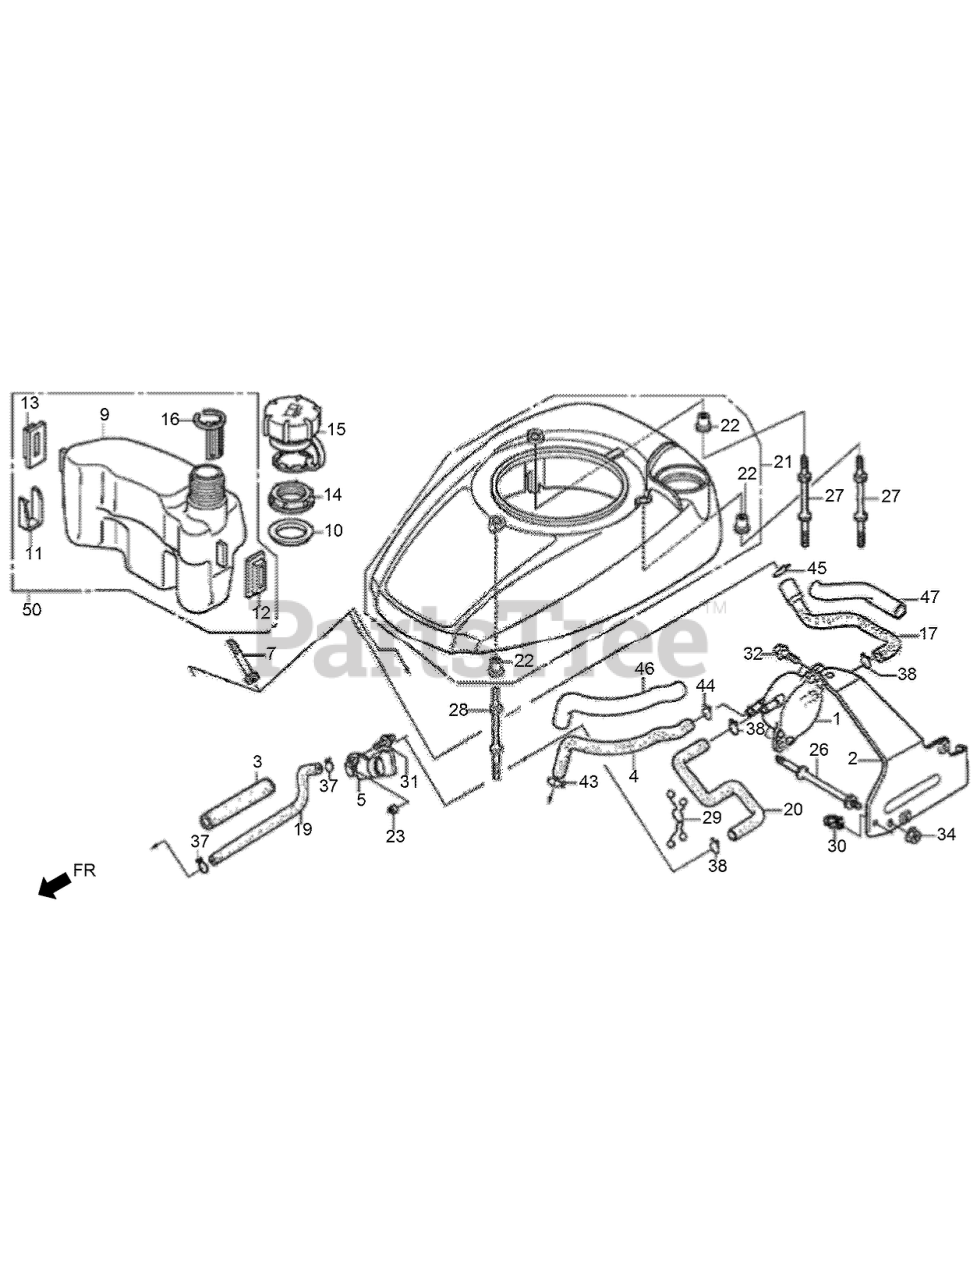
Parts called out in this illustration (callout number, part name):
1	PUMP ASM-FUEL
2	STAY-FUEL PUMP
3	RUBBER-SUPPORTER
4	TUBE-DIAPHRAGM
5	COCK ASM-FUEL
7	STRAINER-FUEL
9	TANK-FUEL (from S/N 3406724)
10	SEAL-FUEL FILLER NECK
11	CLIP-TANK MOUNTING
12	RUBBER A-TANK MOUNTING (from S/N 3406724)
13	RUBBER B-TANK MOUNTING (from S/N 3406724)
14	NUT-TANK MOUNTING
15	CAP ASM-FUEL TANK
16	GAUGE-FUEL LEVEL (from S/N 3406724)
17	TUBE-FUEL TANK
19	TUBE-FUEL
20	TUBE B-FUEL
21	FAN COVER ASM (NH1)
22	COLLAR-FAN COVER
23	COLLAR-FR WINKER
26	BOLT-STUD
27	BOLT-STUD (to S/N 3176791)
27	BOLT-STUD (from S/N 3176792)
28	BOLT-STUD (from S/N 3176792)
28	BOLT-STUD (to S/N 3176791)
29	CLIP-PURSE LOCK
30	CLIP-WIRE HARNESS
31	SCREW-WASHER-5X10
32	SCREW-WASHER-5X14
34	NUT-FLANGE-6MM
37	CLIP-TUBE
38	CLIP-TUBE
43	CLIP-TUBE
44	CLIP-TUBE
45	CLIP-TUBE
46	TUBE-VINYL-9X11X210
47	TUBE-VINYL-13X15X90
50	TANK KIT-FUEL (to S/N 3406723)
